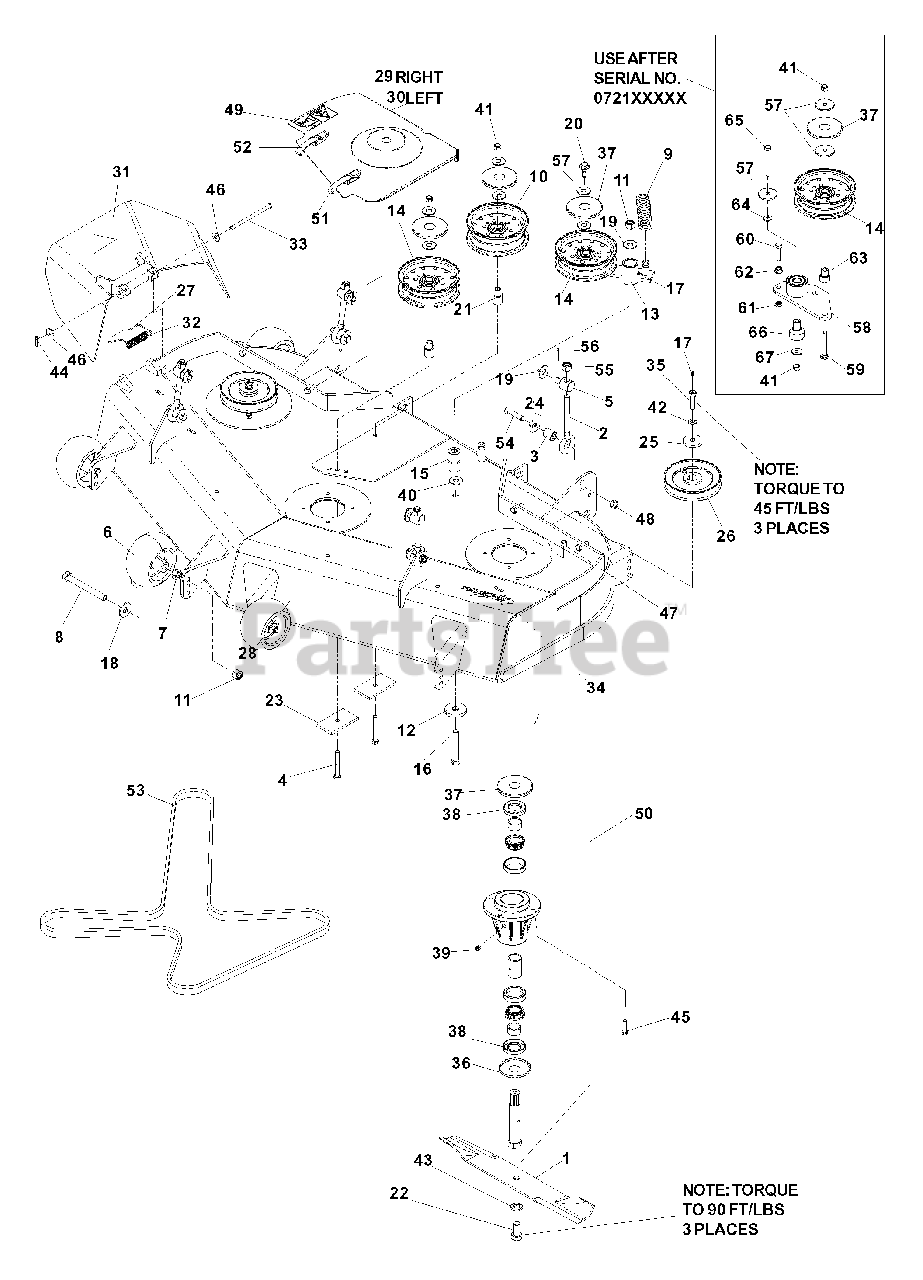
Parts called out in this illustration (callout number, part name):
1	BLADE, 18"
4	HCS, 3/8 -16 x 2 3/4,
6	ROLLER, ANTI SCALP
7	NUT, 1/2 -13
8	HHB, 1/2 -13 x 4
9	SPRING, EXTENSION
10	PULLEY, IDLER
11	NUT, 1/2 -13, NYLOC
14	PULLEY, IDLER
15	BUSHING, PIVOT
16	HCS, 1/2 -13 x 3 1/4,
17	ZERK, STRAIGHT, 1/4 -28
18	WASHER, 1/2
19	WASHER, 9/16
20	HCS, 3/8 -16 x 1,
21	BUSHING, IDLER
22	HCS, 5/8 -18 x 1 1/4,
23	PAD
24	SPRING WASHER, 1/2
25	WASHER,469
27	CAP-SLEEVE
28	DECK W/DECALS
29	BELT SHIELD, RIGHT
30	BELT SHIELD, LEFT
31	DISCHARGE CHUTE
32	SPRING, TORSION
33	PIN-CLEVIS, 5/16 DIA. x 5.19
34	DECAL, TUNNELRAM
35	HCS, 7/16 -20 x 1 1/2, GR8
36	BOTTOM DUST CAP
37	TOP DUST CAP
38	SHAFT SEAL
39	PLUG, VENTED
40	WASHER, 1/2
41	NUT, 3/8 -16, NYLOC
42	LOCKWASHER, 7/16
43	LOCKWASHER, 5/8
44	PIN COTTER, 1/8 x 3/4
45	HCS, 5/16 -18 x 1 1/4,
46	WASHER, 5/16
47	NUT, 5/16 -18, NYLOC
48	NUT, 7/16 -14, CNTRLK, GR A
49	DECAL, EURO SEVERING
50	SPINDLE ASSEMBLY
52	DRAW LATCH
53	DECK BELT
54	HCS, 7/16 -14 x 1 3/4,
55	NUT, 1/2 -13, NYLOC
56	PIN, COTTER, 1/8 x 1
57	WASHER, 3/8 , SPEC
58	ARM, IDLER, W/BEARINGS
59	RHSNB, 3/8 -16 x 2 3/4,
60	HCS, 3/8 -16 x 1 1/2, GR8
61	NUT, 3/8 -16, JAM
62	NUT, 3/8 -16, WHIZLK
63	BUSHING, IDLER
64	WASHER, 3/8 , SAE
65	HCS, 3/8-16 x 3,
66	PIVOT, BEARING
67	WASHER, 3/8
